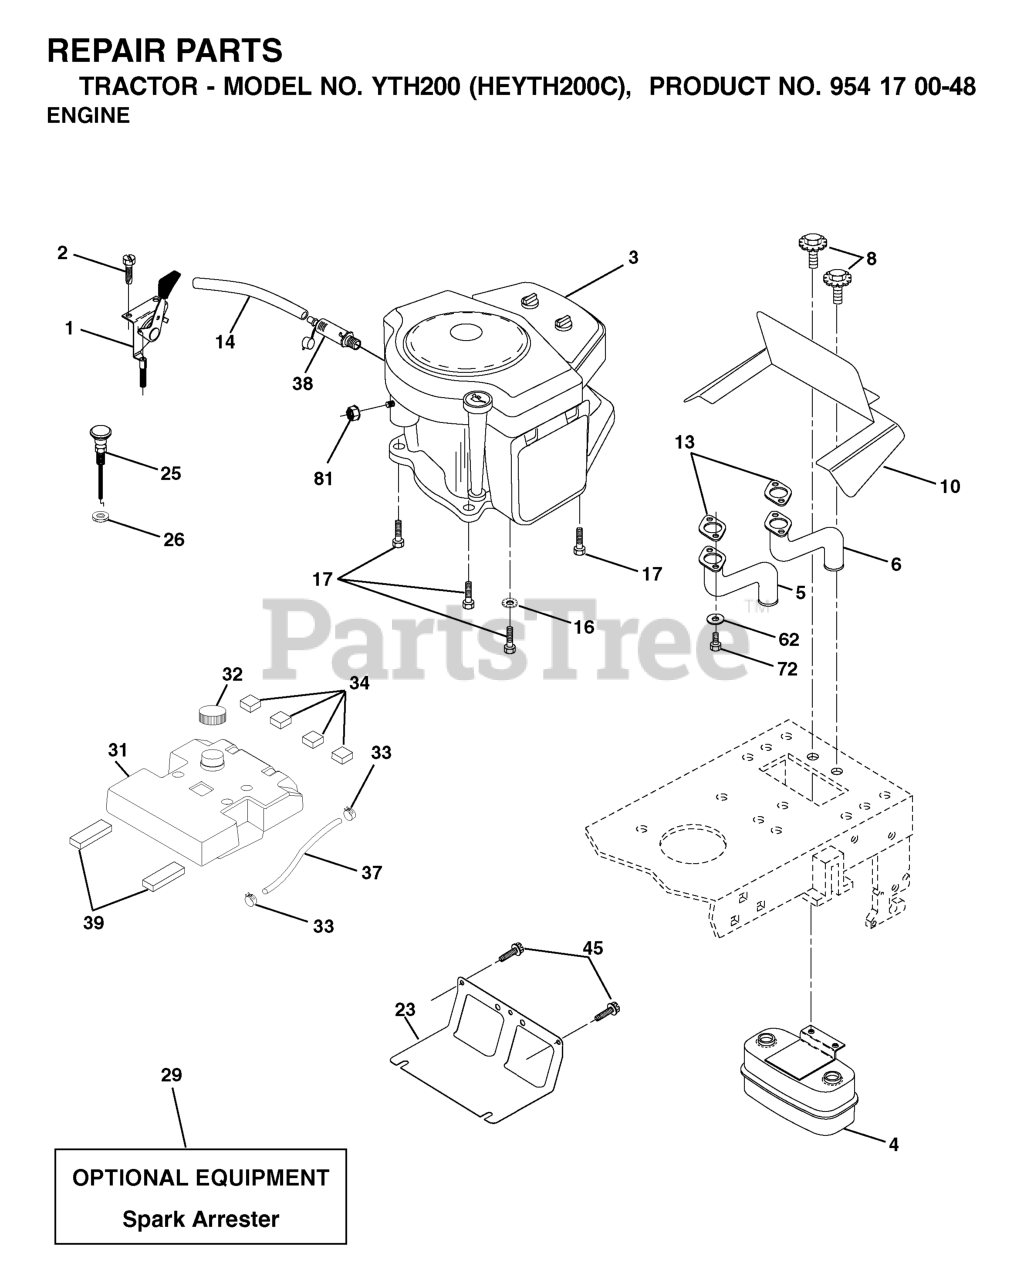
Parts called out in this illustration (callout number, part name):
1	CONTROL, THROTTLE
2	SCREW
4	MUFFLER.TWIN.CYL.LOW.TONE
5	RP.EXHAUST.TUBE.LH.BS/TWIN
6	EXHAUST.TUBE.RH.BS/TWIN
8	BOLT.5/16-18UNCX3/4 W/SEMS.BLK
10	SHIELD.BROWNING.B&S
13	GASKET.MUFFLER
14	TUBE, DRAIN OIL ASM.
16	LOCKWASHER
17	SCREW 3/8-16 X 1-1/2
23	SHIELD.BROWNING.DBR.GUARD
25	CONTROL, CHOKE
26	Nut Keps 3/8 - 24 UNF
29	KIT.SPARK ARRESTOR 794945 B&S
31	TANK.FUEL(3.5.GAL)
32	FUEL CAP
33	HOSE CLAMP
34	PAD-SPACER LT
37	REPL BY 532 00 85-43
38	PLUG DRAIN OIL EASY
39	PAD IDLER TI
45	SCREW, 3/8-16X3/4
62	WASHER.LOCK.HVY.HLCL.SPR.5/16
72	SCREW
81	NUT
